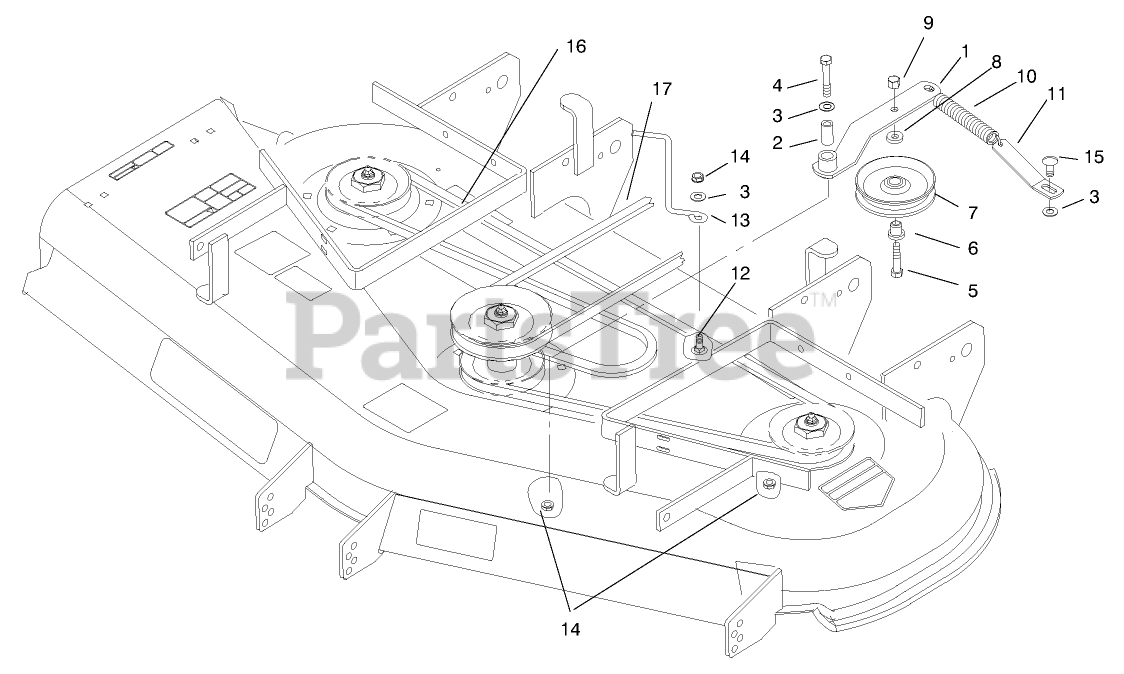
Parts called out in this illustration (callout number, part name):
1	IDLER ARM ASM
2	SLEEVE
3	WASHER-FLAT
4	SCREW-HH
5	SCREW-HH
6	BUSHING-PULLEY
7	PULLEY-IDLER
8	WASHER-FLAT
9	NUT-HEX
10	SPRING-EXTENSION
11	PLATE-SPRING
12	SCREW-CARR
13	GUIDE-BELT
14	NUT-HF
15	BOLT-CARR
16	V-BELT
17	V-BELT, DRIVE
